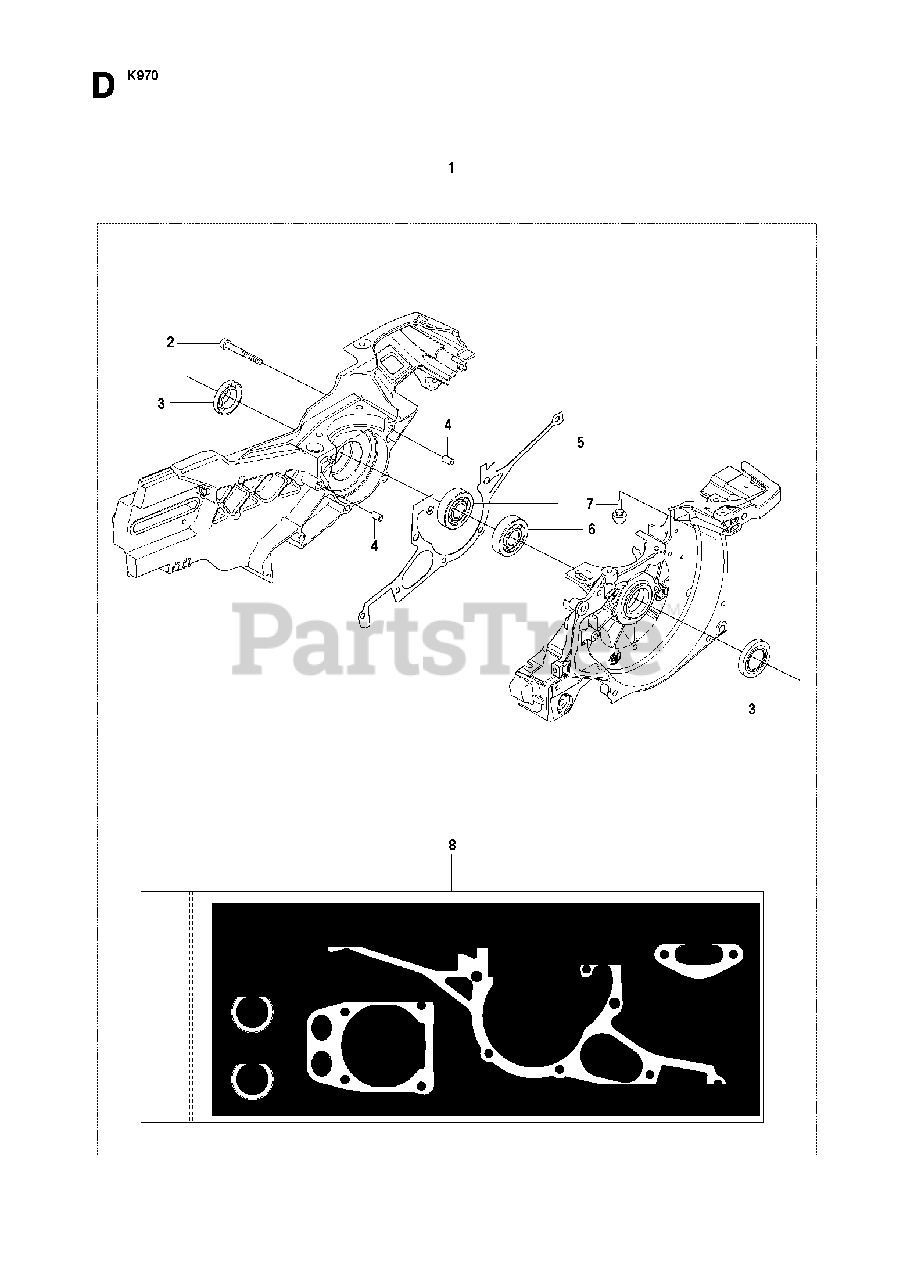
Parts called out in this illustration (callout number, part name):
2	SCREW ITXSCM
3	SEALING RING
4	GUIDE BUSHING
6	BALL BEARING
7	RUBBER BUSHING
8	GASKET KIT
10	GASKET
